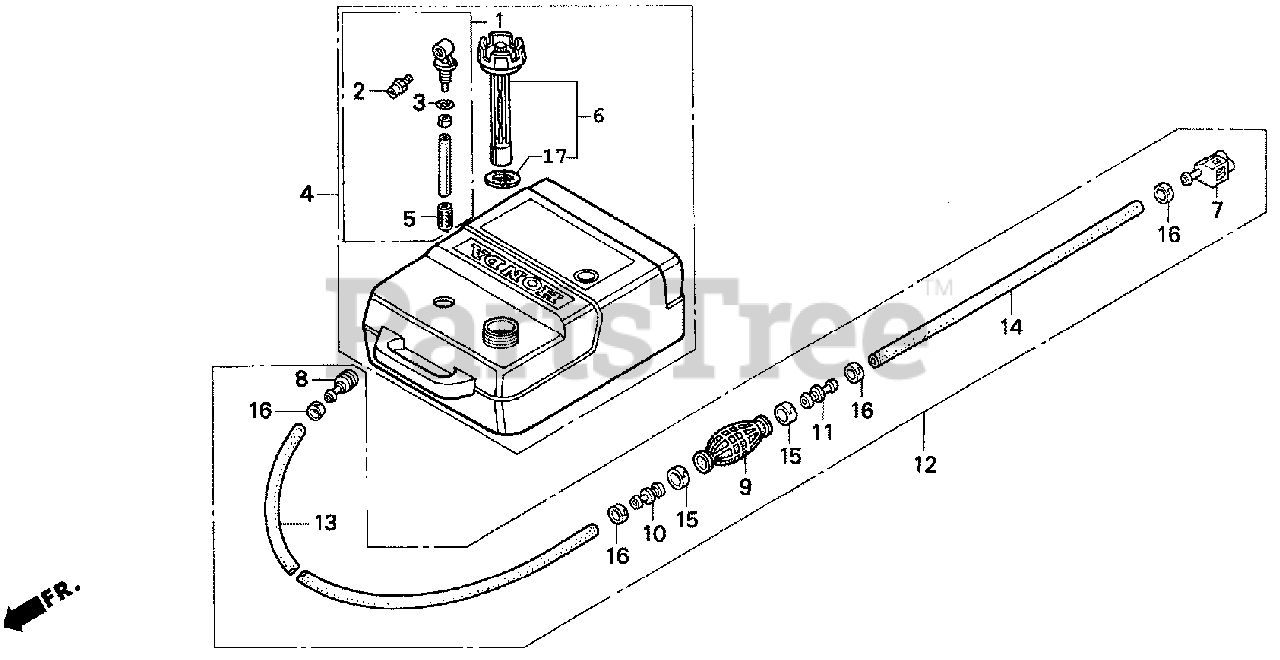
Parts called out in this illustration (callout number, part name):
1	JOINT ASSY., FUEL
2	FITTING, QUICK DISCONNECT
3	O-RING
4	TANK ASSY., FUEL
5	FILTER, FUEL
6	CAP, FUEL FILLER
7	CONNECTOR SET, FUEL
7	CONNECTOR ASSY. A, FUEL
8	CONNECTOR, FUEL
9	PRIMER BULB
10	VALVE, IN.
11	VALVE, OUTLET
12	TUBE ASSY., FUEL
13	TUBE, FUEL (7.5X2000)
14	TUBE, FUEL SHORT
15	BAND, TUBE CLIP (20MM)
16	BAND, TUBE CLIP (12.5MM)
17	GASKET, FUEL CAP
